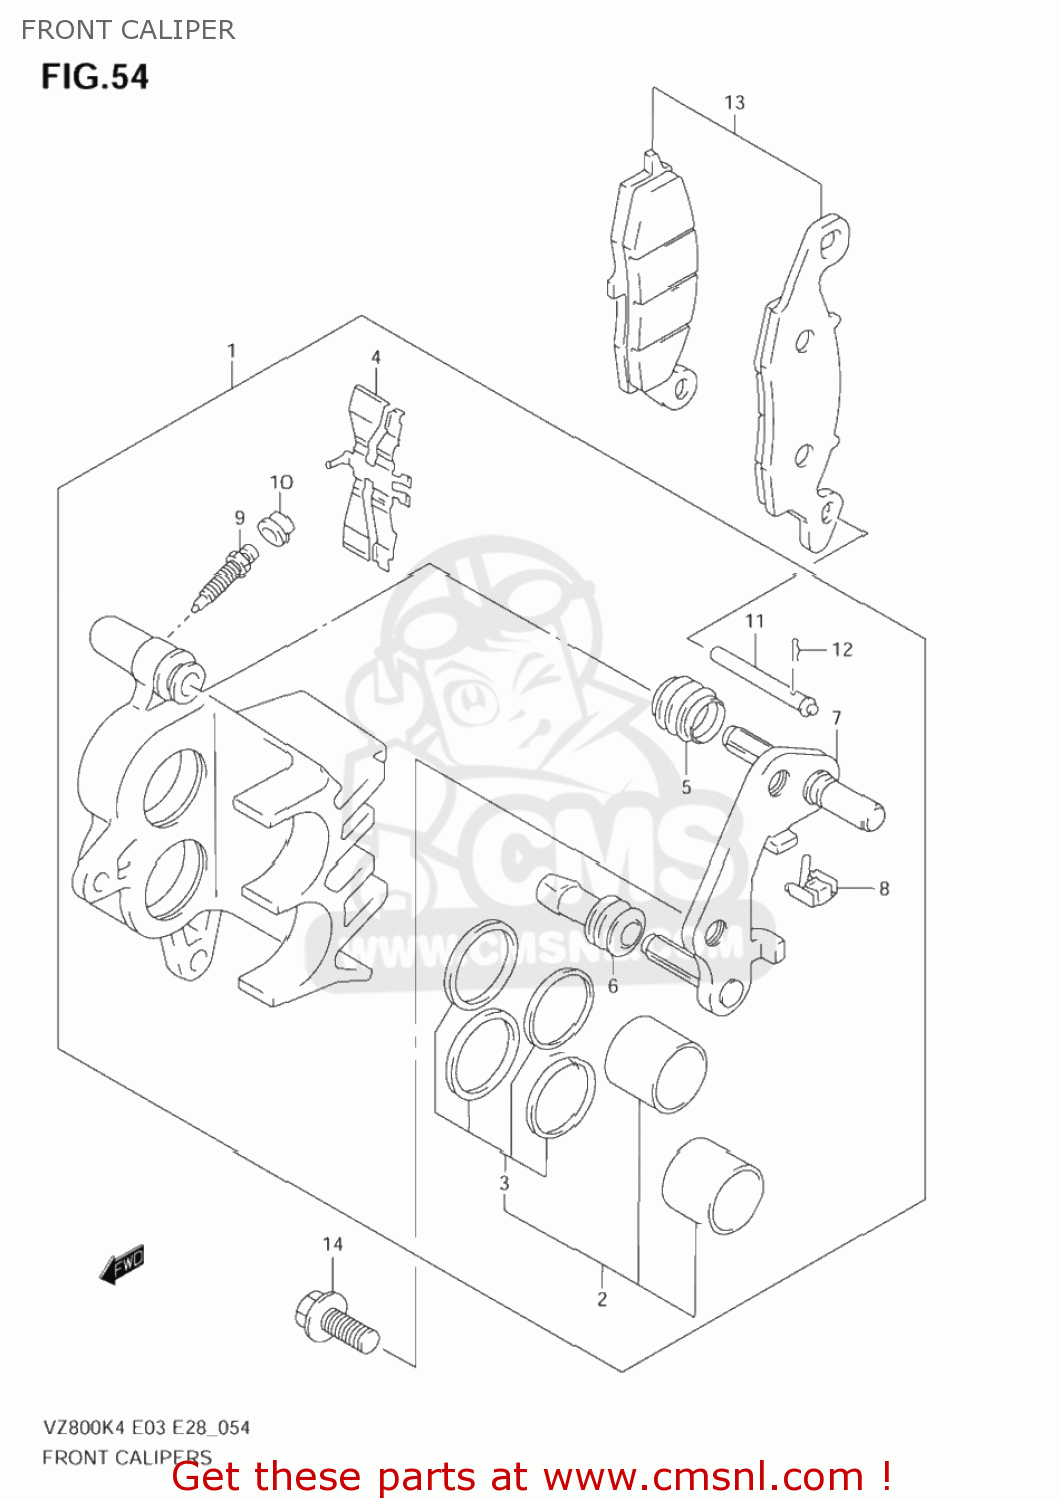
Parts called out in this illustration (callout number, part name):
1	CALIPER ASSY, FRONT RH
2	PISTON SET
3	SEAL SET,PISTON
4	SPRING,PAD,R
5	BOOT,AXLE
6	INSULATOR,AXLE
7	CARRIER,CALIPER,R
8	GUIDE,PAD
9	BLEEDER
10	CAP,BLEEDER PLUG
11	PIN,PAD
12	CLIP,PAD PIN
13	PAD SET (NAS)
14	BOLT
